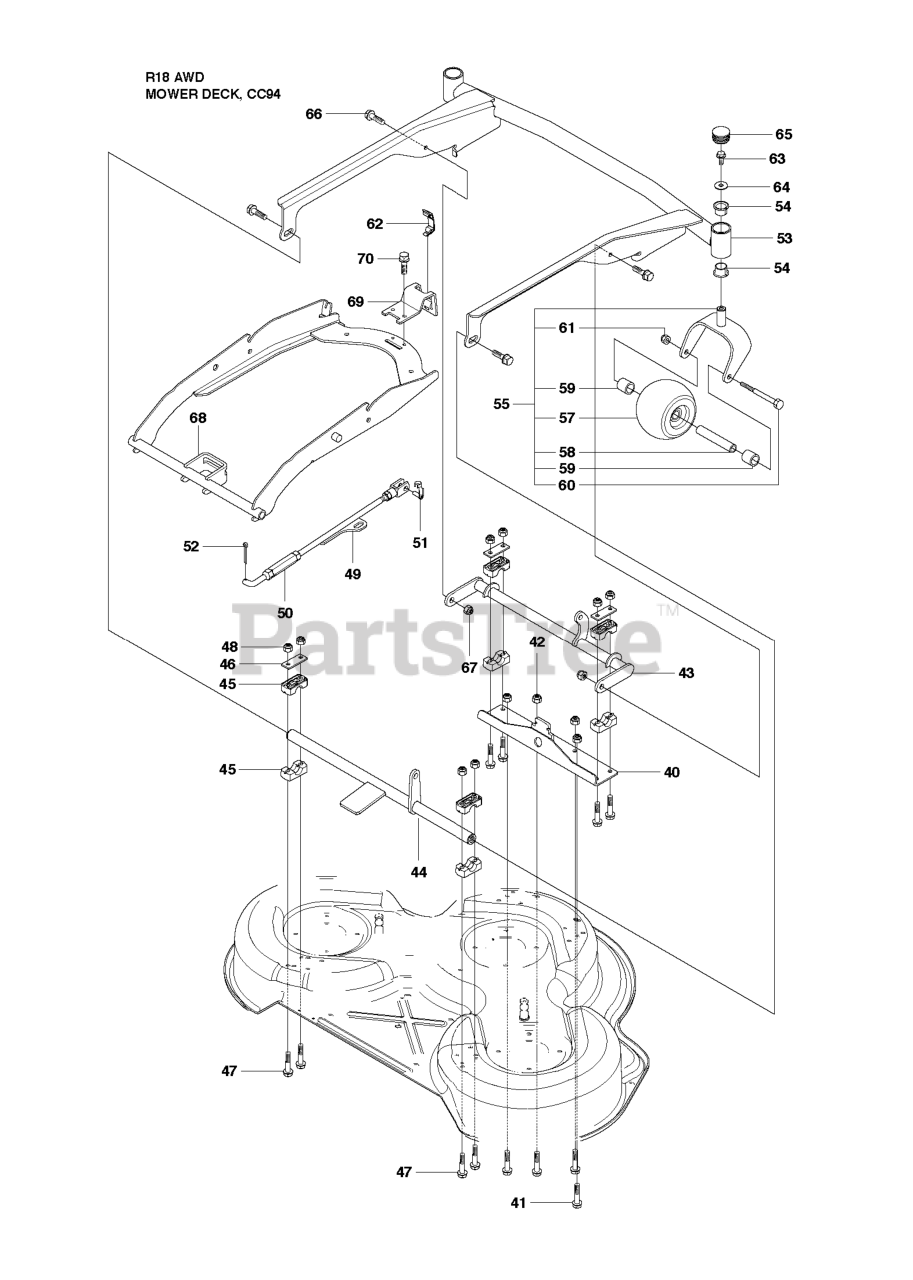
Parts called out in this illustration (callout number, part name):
42	LOCKNUT M8
48	LOCKNUT M8
49	PARALLELL ROD ASSY
50	PARALLEL ROD
51	RETAINER
53	DECK FRAME
55	PIVOT WHEEL ASSY
57	DECK ROLLER, FRONT
61	NUT
62	CLIP GRAY
67	LOCKNUT M8
68	DECK ATTACHMENT
70	SCREW
